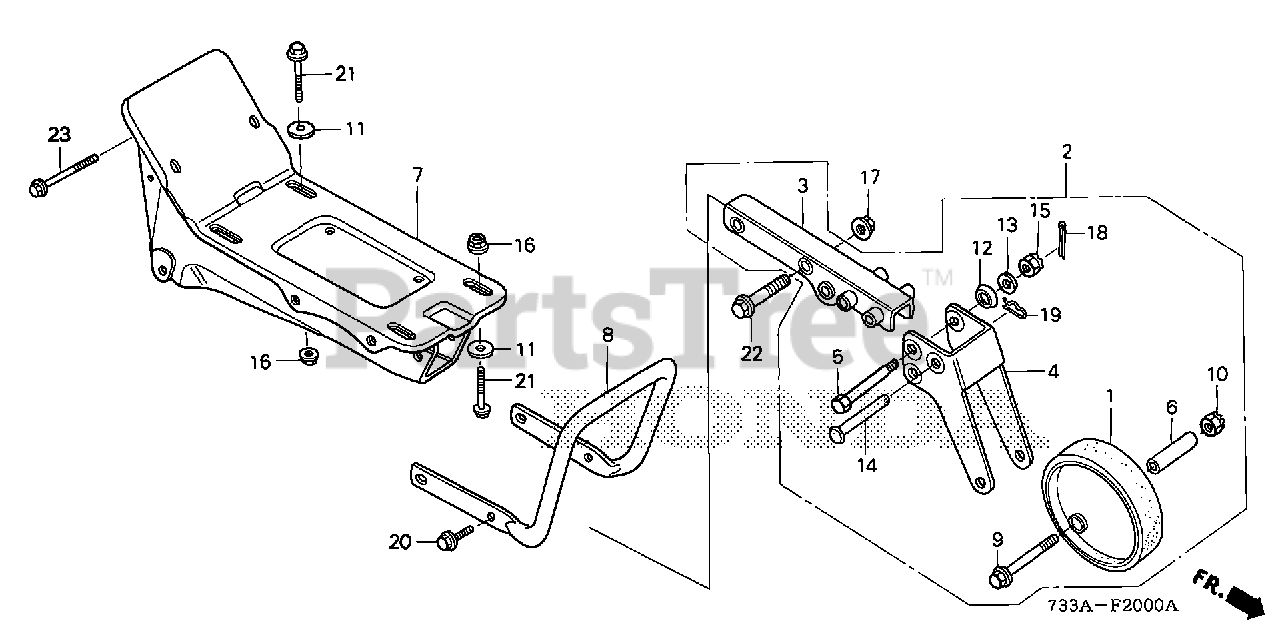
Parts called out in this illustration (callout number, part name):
1	WHEEL, RR.
2	WHEEL ASSY., FR.
3	BEAM, FR. WHEEL
4	ARM, FR. WHEEL
5	SHAFT, FR. WHEEL
6	SHAFT, FR. WHEEL PIPE
7	BED, ENGINE
8	PIPE, FR. GUARD
9	BOLT, FLANGE (8X75)
10	NUT, SELF-LOCK (8MM)
11	WASHER (8X22)
12	WASHER, CHUTE GUIDE
13	WASHER, PLAIN (10MM)
14	PIN (10X70)
15	NUT, SELF-LOCK (8MM) (SOURCE: VINTAGE PARTS INC.)
16	NUT, FLANGE (8MM)
17	NUT, FLANGE (10MM)
18	PIN, SPLIT (2.0X22)
18	PIN, SPLIT (2.0X35)
19	PIN, LOCK (10MM)
20	BOLT, FLANGE (8X16)
21	BOLT, FLANGE (8X35)
22	BOLT, FLANGE (10X40)
23	BOLT, FLANGE (8X65)
